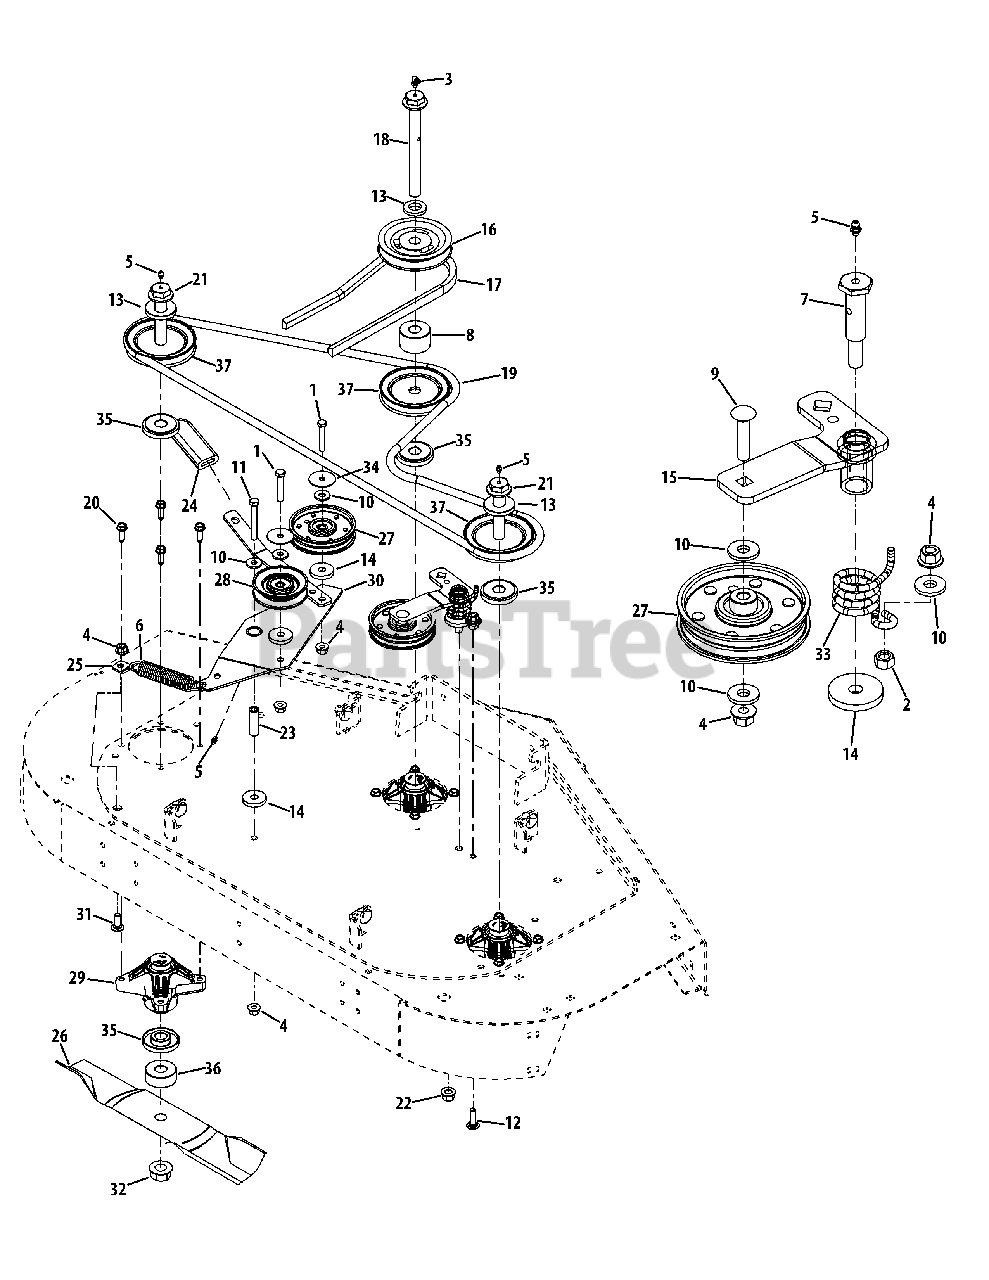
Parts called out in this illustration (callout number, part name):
1	Hex Screw, 3/8-16 x 2.00
2	Nut, 3/8-16
3	Grease Fitting, 1/4-28 x .788
4	Counterlock Flange Nut, 3/8-16
5	Grease Fitting, 1/4-28
6	Extension Spring, 1.00 x 5.00 x .125
7	Shoulder Bolt, .625 x 1.95
8	Spacer, .760 x 2.00 x 1.27
9	Carriage Bolt, 3/8-16 x 1.75
10	Washer, .406 x 1.00 x .105
11	Hex Screw, 3/8-16 x 3.00
12	Carriage Bolt, 3/8-16 x 1.25
13	Spacer, 2.0 x .75 ID x .31
14	Washer, .470 x 1.50 x .225
15	Idler Arm Assembly
15	Sleeve Bearing, .638 x .753 x .615
17	V-Belt
18	Hex Screw, 3/4-16 x 7.7
20	Hex Flange Screw, 5/16-18 x 1.00
21	Hex Flange Screw, 3/4-16 x 5.625
22	Flange Lock Nut, 7/16-14
23	Spacer, .390 x .625 x 1.88
24	Flat Grip, 1.0 x 3.2 x .25
25	Spring Mount Bracket
26	Hi-Lift Blade, 19.0
27	Idler Pulley
28	Idler Pulley
29	Spindle Assembly
30	Double Idler
30	Sleeve Bearing, .638 x .753 x .615
31	Carriage Bolt, 3/8-16 x 1.00
32	Flange Lock Nut, 3/4-16
33	Torsion Spring
34	Washer, .406 x 1.92 x .060
35	Deck Spindle Spacer
36	Spacer, .760 x 2.000 x .790
